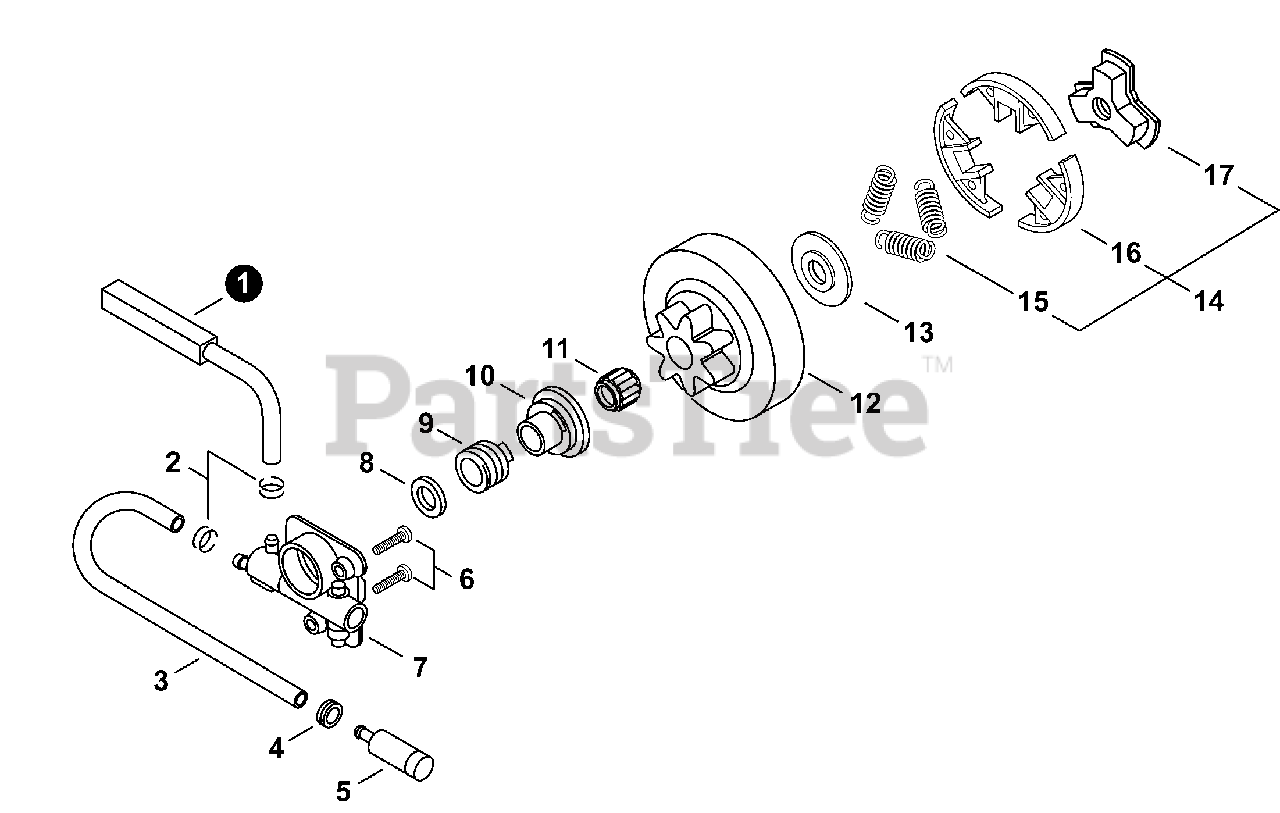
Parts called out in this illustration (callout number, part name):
1	PIPE, OIL OUTLET
2	CLIP Ø6.5 MM
3	PIPE, OIL
5	FILTER, OIL
6	SCREW 4×12
7	AUTO-OILER ASSY
8	WASHER 10.5×17.4×1.8
9	GEAR, WORM
10	COLLAR 10
11	BEARING, NEEDLE 10
12	DRUM, CLUTCH
13	PLATE, CLUTCH
14	CLUTCH ASSY
15	SPRING, TENSION
16	SHOE SET, CLUTCH (3PCS)
17	HUB, CLUTCH
